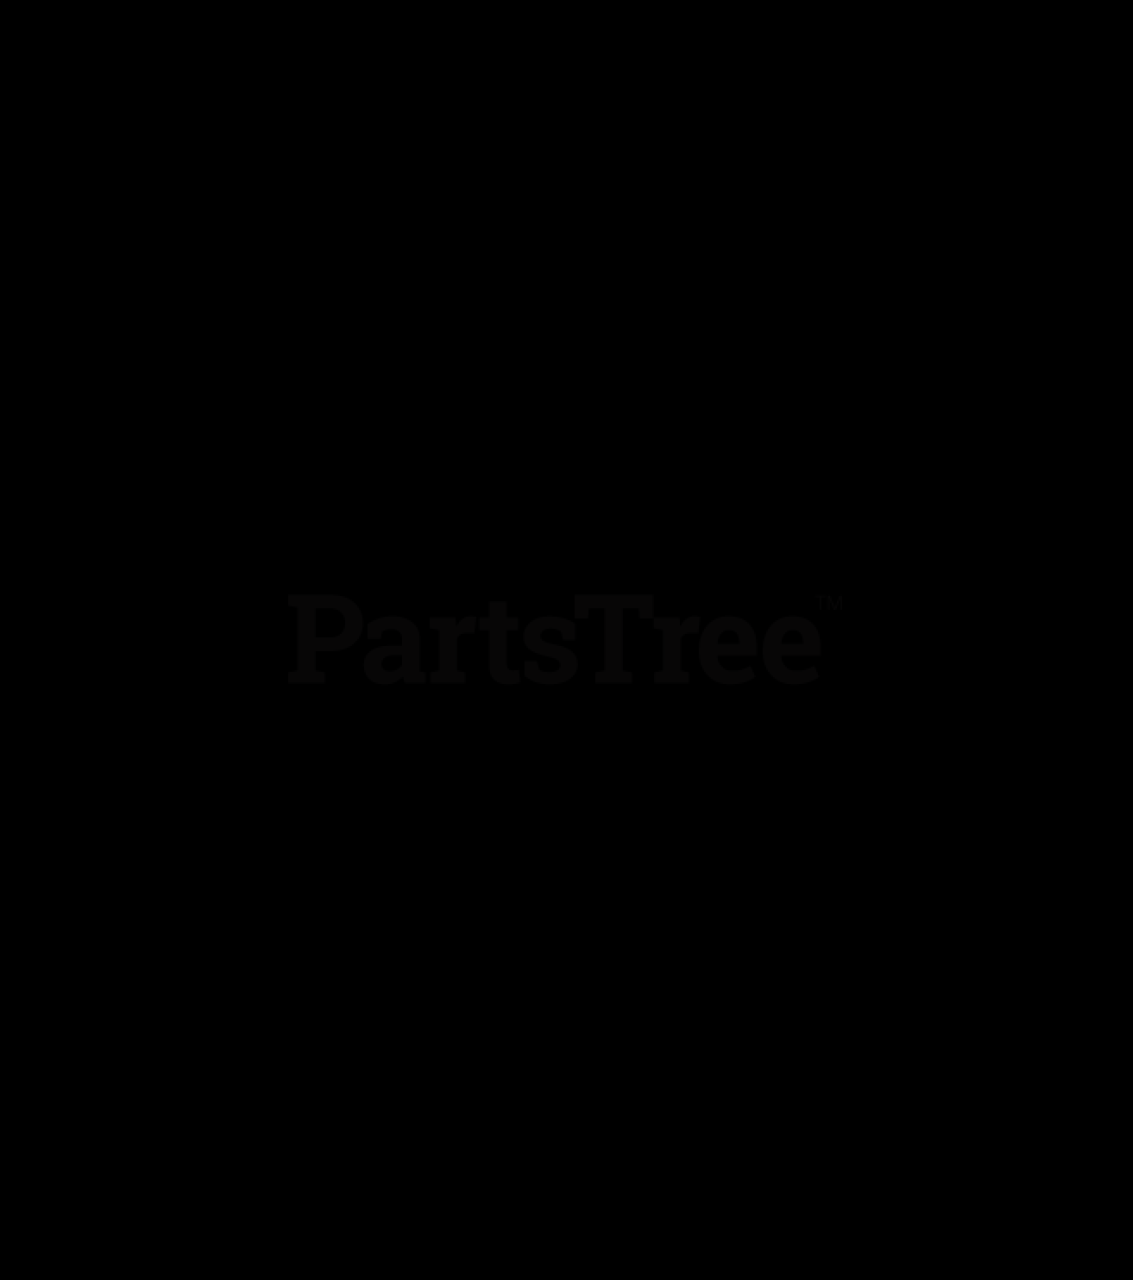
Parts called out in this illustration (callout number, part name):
1	Retainer, Grease
2	Spindle
3	Bolt, Hex .375-16 x 1
4	Washer, Belleville .63 x 1.625 x .14
5	Lock Washer, Spring Regular
6	Bolt, Hex .62-18 x 1.75
7	Blade, 20.83" Mower (Counterclockwise Rotation)
8	Blade, 20.83"
9	Housing, Spindle (G5000)
10	Bolt, Hex .31-18 x 1.00 Grade 5
